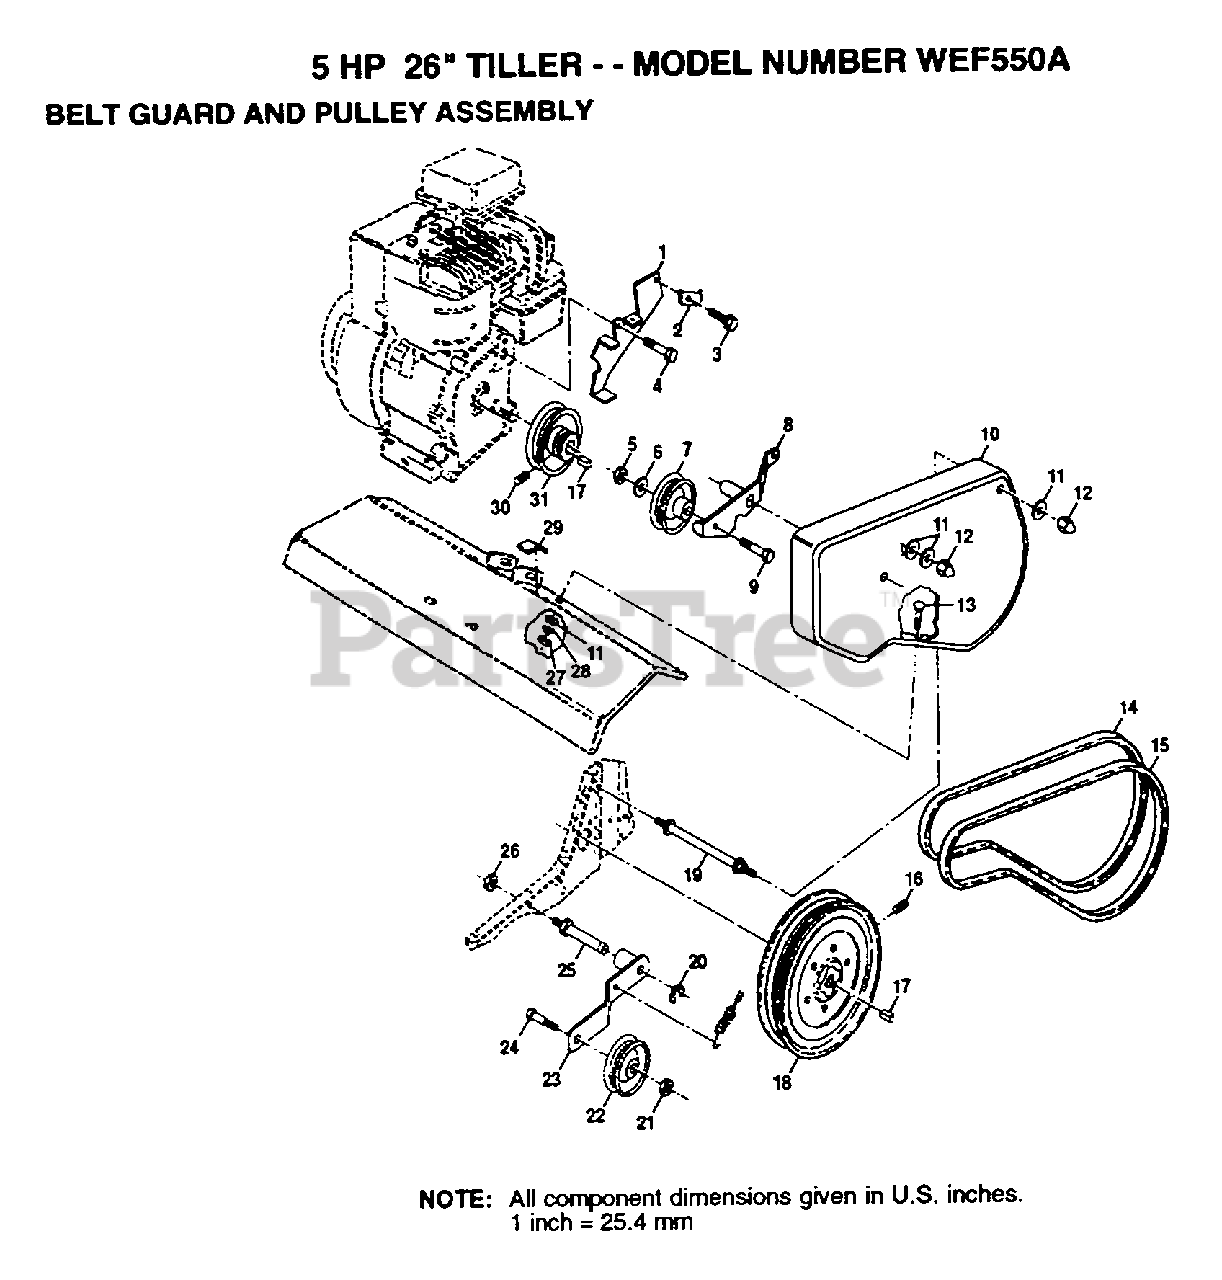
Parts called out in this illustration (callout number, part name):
2	CONDIUT CLIP T
5	NUT.HEX.3/8-16UNC
6	PULLEY W/SPACER
7	ARM.ASM.REV.IDLER
10	WASHER
11	NUT-CAP TI
12	BOLT T
13	BELT-V
15	SET SCREW
17	KEY T
18	BOLT TI
19	KLIP RING TI
20	NUT
22	IDLER ARM TI
24	SHAFT IDLER TI
25	JAM NUT TI
27	LOCKWASHER
28	PAD IDLER TI
29	SET SCREW
30	ENGINE PULLEY TI
31	WASHER
